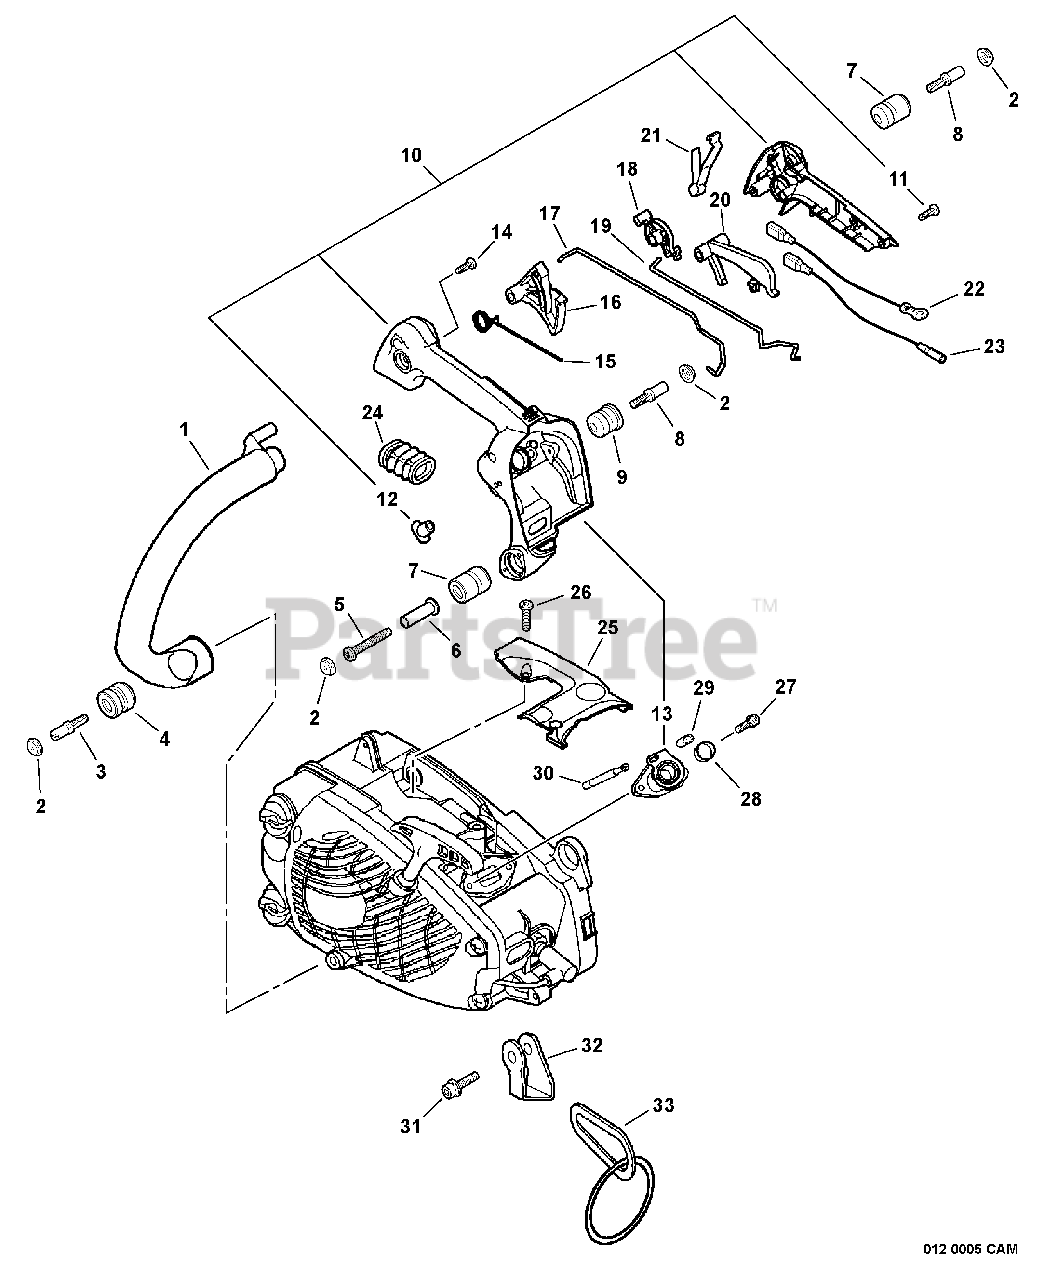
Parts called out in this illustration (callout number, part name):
1	HANDLE, FRONT
2	CAP, CUSHION
4	CUSHION 5
5	SCREW, TAPPING 4×35
6	COLLAR 4
7	CUSHION
8	BOLT 4×15
9	CUSHION
10	HANDLE KIT, REAR
11	SCREW 4×16
13	BELLOWS, INTAKE
14	SCREW, TAPPING 5×20
15	SPRING, TORSION
16	TRIGGER, THROTTLE
17	ROD, THROTTLE
18	LEVER, CONTROL
19	ROD, CHOKE
20	LOCKOUT, THROTTLE
21	TERMINAL, LEAD
24	BELLOWS, INTAKE
25	COVER, DUST
26	SCREW 4×12
27	SCREW 5×12
28	COLLAR 16
29	COLLAR Ø3.2×6.5
30	PIPE, PULSE 3×7×65
31	BOLT 4×25
32	BRACKET, HARNESS
33	RING, HARNESS
